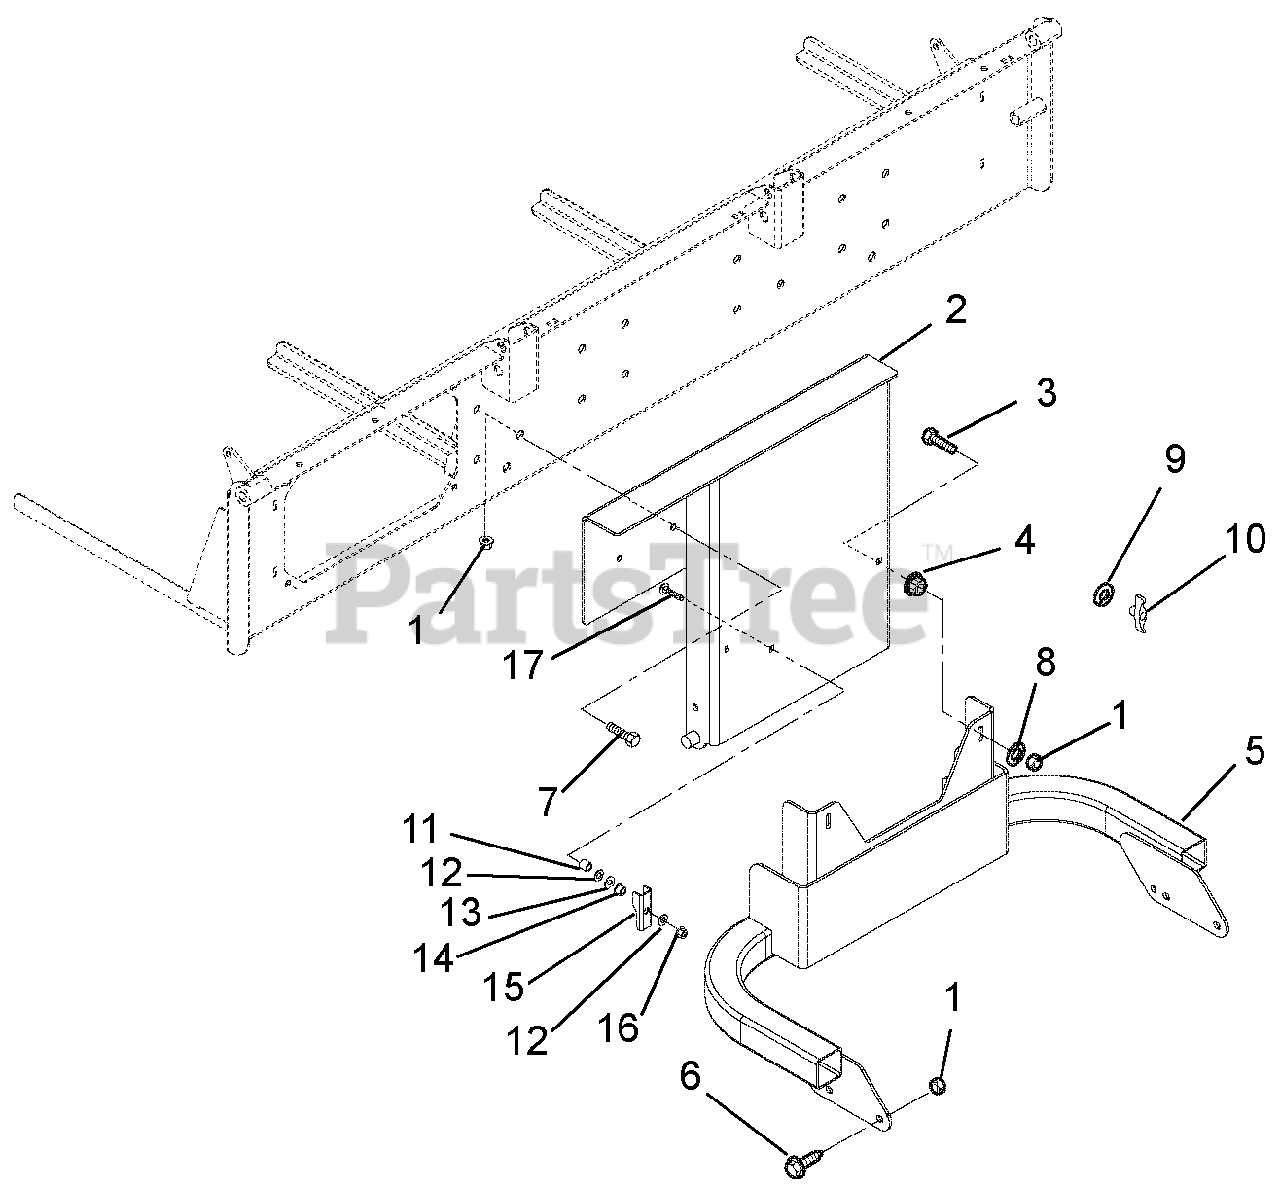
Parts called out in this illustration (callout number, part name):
1	Nut, .38-16 Nyloc Flange
2	Upper Mount, 3-Bag
3	Bolt, Round Head Square Neck .38-16 x 1.75 Grade 5
4	Nut, Spinlock Flange .375
5	Mount, Bagger 200 Series
6	Bolt, Hex .38-16 x 3.25 Grade 5
7	Bolt, Hex .38-16 x 1.00 Grade 5
8	Washer, Flat Steel .406 x 1.50 x .245
9	Washer, Locking .375 x .115 Heavy (Tool-less hardware option)
10	Nut, Wing .38-16 (Tool-less hardware option)
11	Spacer .41 x .75 x .88
12	Washer, Flat Steel .438 x 1.00 x .083
13	Wave Washer .640 x .875 x .125 Free Height
14	Bushing, Sleeve .377 x .624 x .235
15	Latch, Bagger Upper Mount
16	Nut, Locking Top Flange .38-16
17	Bolt, Round Head Square Neck .38-16 x 2.00 Grade 5
